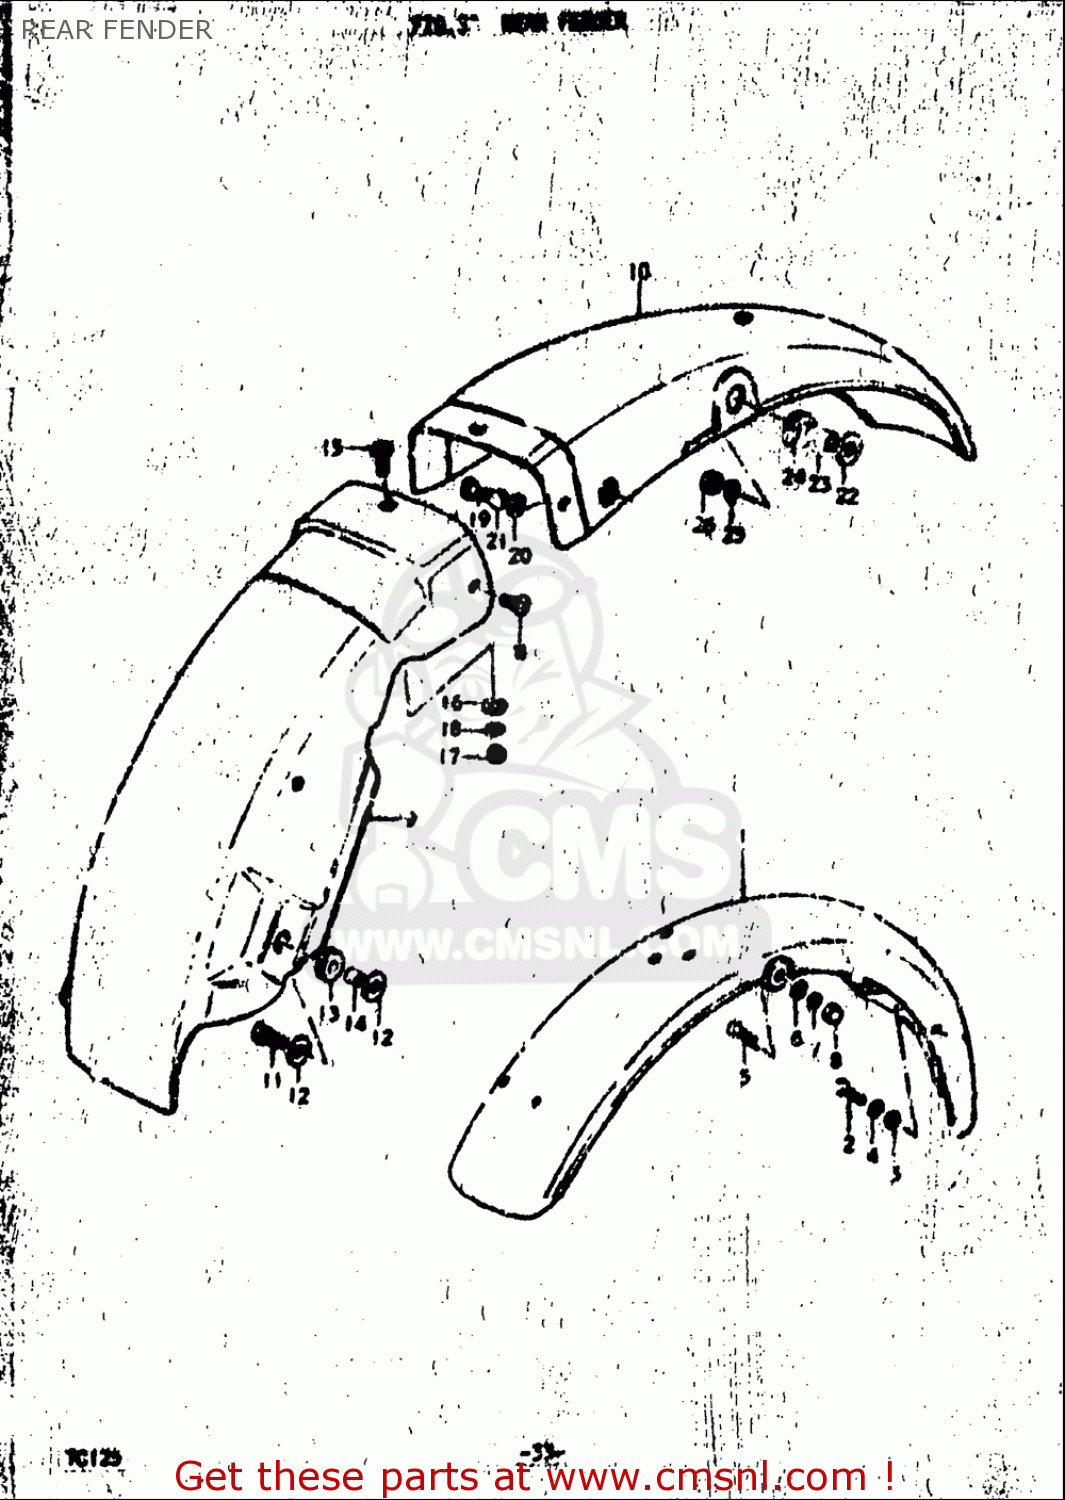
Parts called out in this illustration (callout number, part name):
2	BOLT(8X16)
3	WASHER
4	WASHER,LOCK
5	BOLT(8X16)
6	WASHER
7	WASHER,LOCK
8	NUT
11	BOLT
12	WASHER(6.5X20X1.2)
13	CUSHION
14	SPACER(6.1X9X7.5)
15	SCREW
16	WASHER
17	NUT
18	WASHER,LOCK
19	BOLT
20	WASHER
21	WASHER,LOCK
22	WASHER(10.3X25X1.5
23	SPACER
24	CUSHION
25	WASHER,LOCK
26	NUT
